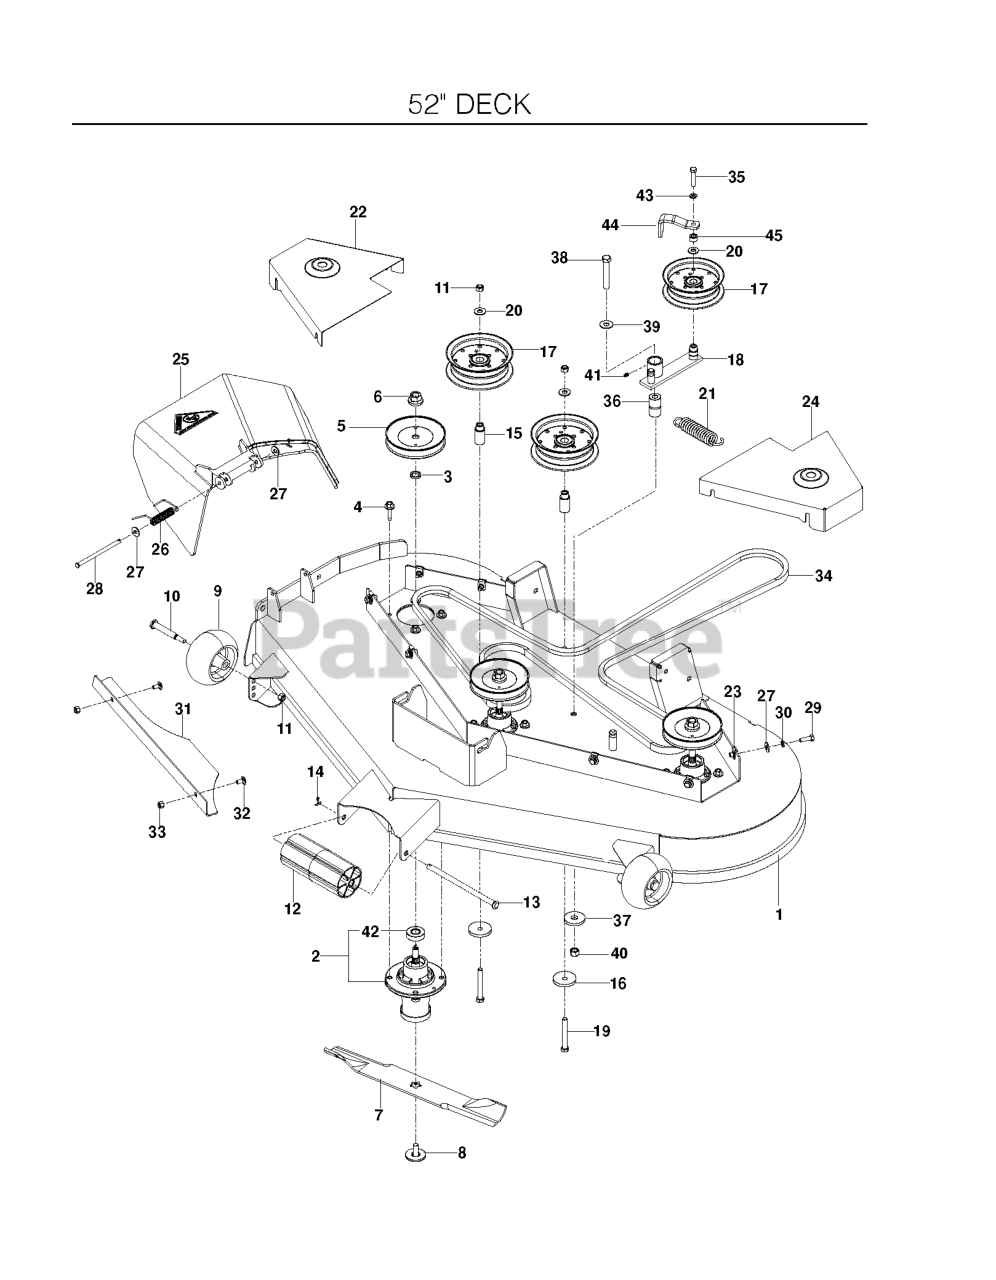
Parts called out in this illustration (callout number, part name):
1	DECK.SVC.W/DECALS.EZ52
2	MANDREL.DECK.ASSEMBLY
3	WASHER-SPACER
4	WASHER HEAD SCREW
5	PULLEY
6	LOCKNUT - 9/16
7	BLADE, 18"
8	BLADE BOLT ASSY-7/16" TB REPL
9	GAUGE WHEEL
10	SHOULDER BOLT 1/2X2-5/8 ZD SPE
11	NUT 3/8-16 NYLOC
12	NOSE ROLLER 48"
13	NOSE ROLLER ROD
14	RP_COTTER PIN 1/8 X 3/4
15	IDLER BUSHING
16	SPINDLE WASHER
17	PULLEY, IDLER
19	HCS 3/8C X 3
20	WASHER 3/8 FLAT
22	BELT SHIELD, RIGHT 52, ORG
23	U-CLIP 5/16-18 NUT RETAINER
24	BELT SHIELD, LEFT 52, ORG
25	DISCHARGE CHUTE 52"
26	SPRING - TORSION
27	WASHER 5/16 FLAT
28	PIN-CLEVIS 5/16 DIA X 5.19 ZD
29	HCS 5/16C X 1
30	WASHER.LOCK.HVY.HLCL.SPR.5/16
31	CONFINEMENT PLATE, 52"
32	CARRIAGE BOLT 5/16C X 5/8"
33	NUT 5/16 NYLOC
34	BELT, DECK
35	HCS 3/8-16 X 1 3/4 GR5
36	PIVOT BUSHING
37	WASHER, SUPPORT
38	HCS 1/2C X 3 1/4
39	WASHER 1/2 FLAT
40	NUT 1/2-13 HEX NYLOC ZD
41	ZERK
42	BEARING, BALL
43	SLW 3/8 STD
44	GUIDE, BELT
